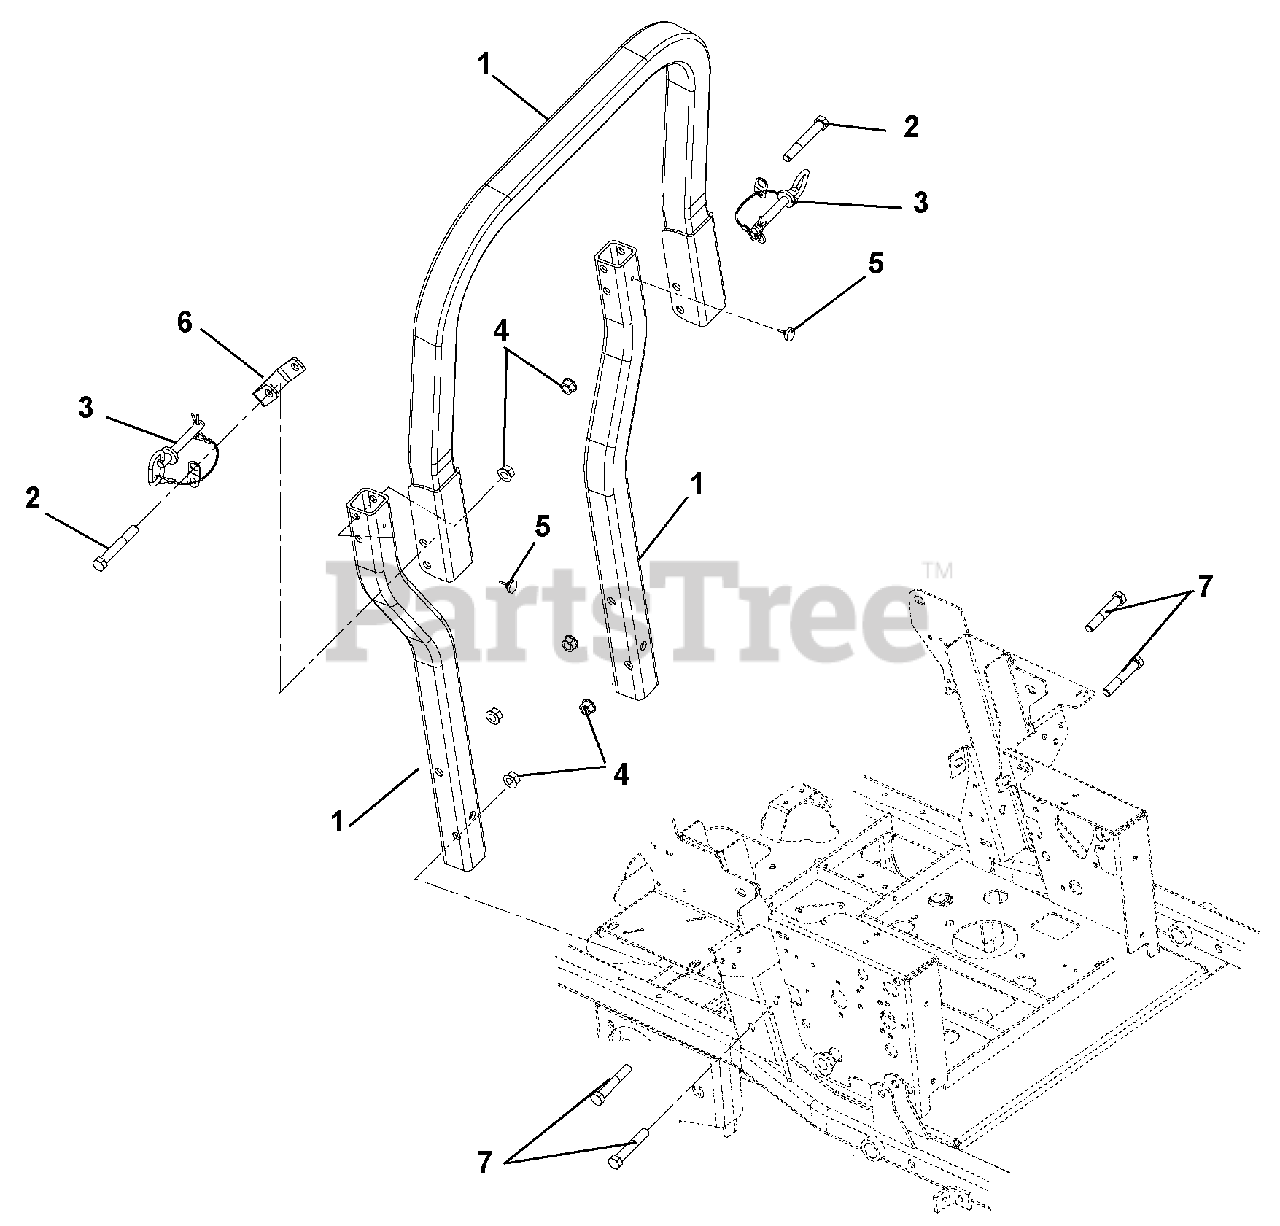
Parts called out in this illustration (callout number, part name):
1	ROPS, PM200 Replacement Kit
2	Bolt, Hex .50-13 x 3.50 Grade 5
3	Assembly, ROPS PIN/LANYARD
4	Nut, Locking-Top-Flange .50-13
5	Bumper, ROPS Rubber
6	Bracket, ROPS Stop, Pro-Master
7	Bolt, Hex .50-13 x 3.00 Grade 5
